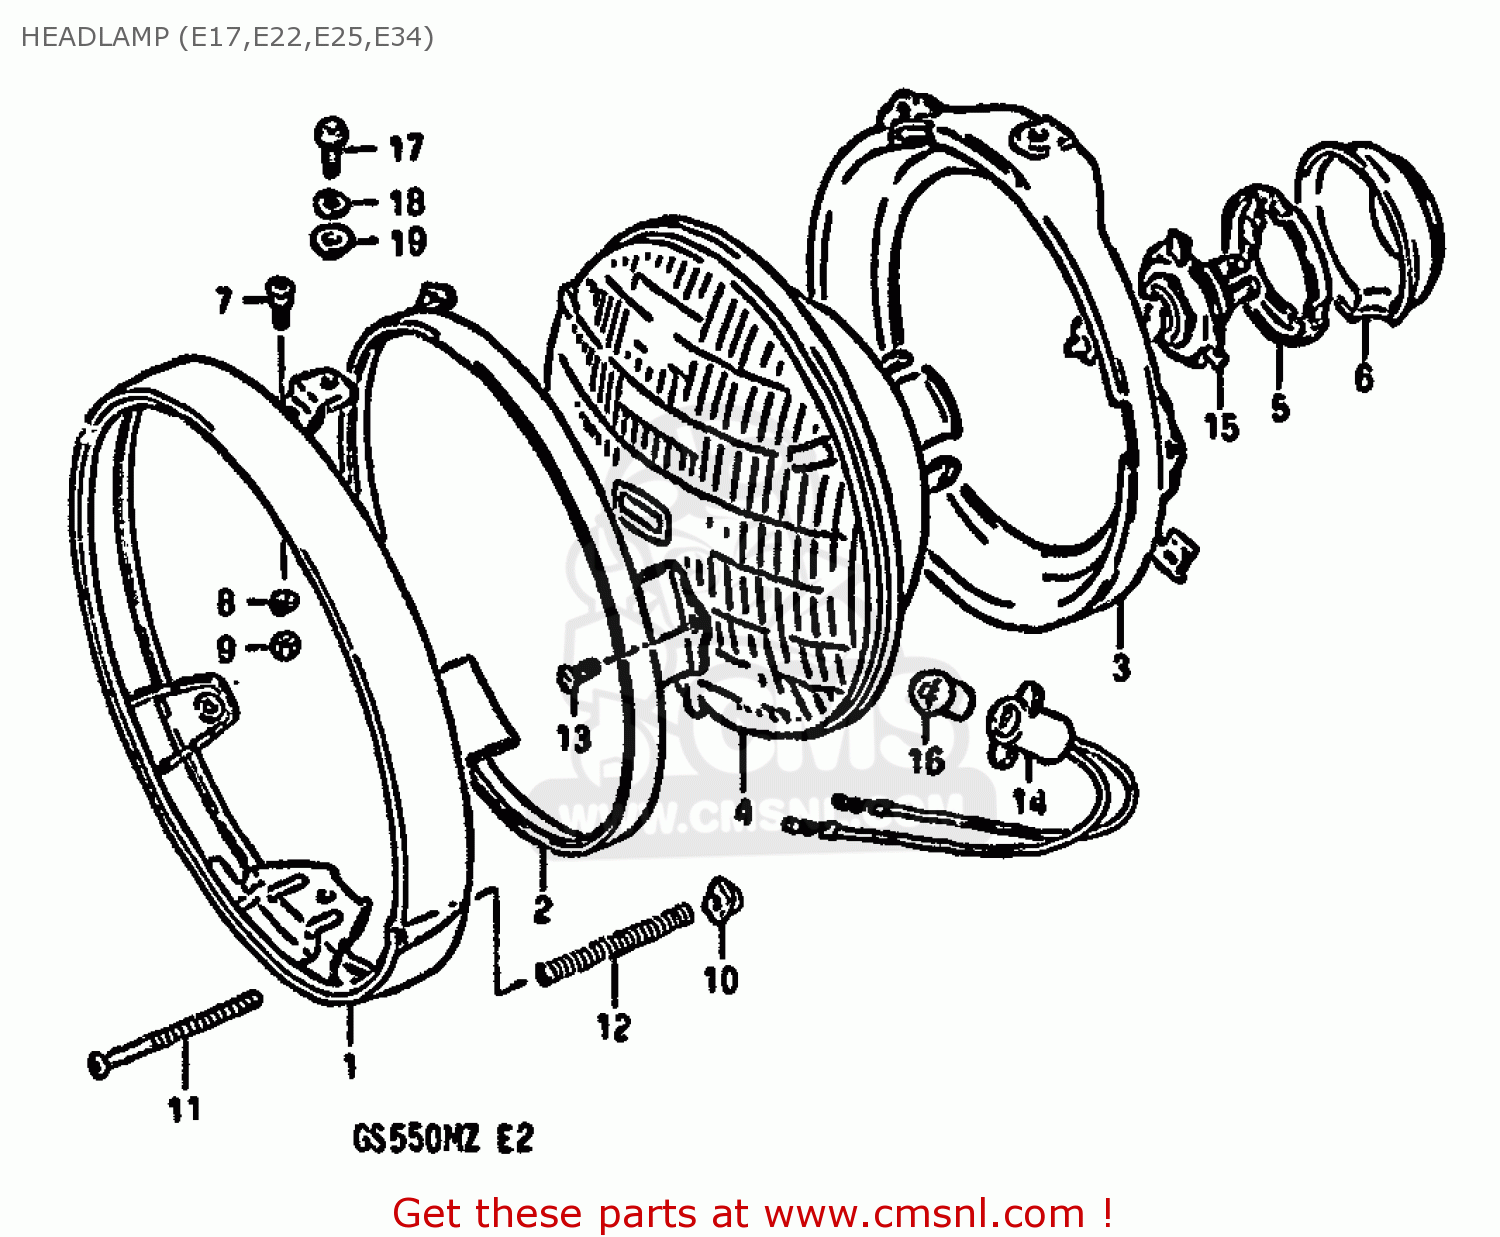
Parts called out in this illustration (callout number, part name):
1	RIM,HEADLAMP
2	RETAINING RING
3	RING
4	UNIT,HEAD LAMP
5	SETTING,BULB
6	COVER,HEADLAMP SOCKET
7	H/LAMP LENS UNIT FITING SCRE
8	LOCK WASHER
9	NUT
10	NUT
11	SCREW
12	SPRING,ADJUSTING
13	SCREW
14	SOCKET
15	BULB(12V60/55W,H4)
16	BULB(12V4W)
17	SCREW
18	WASHER,LOCK
19	WASHER
